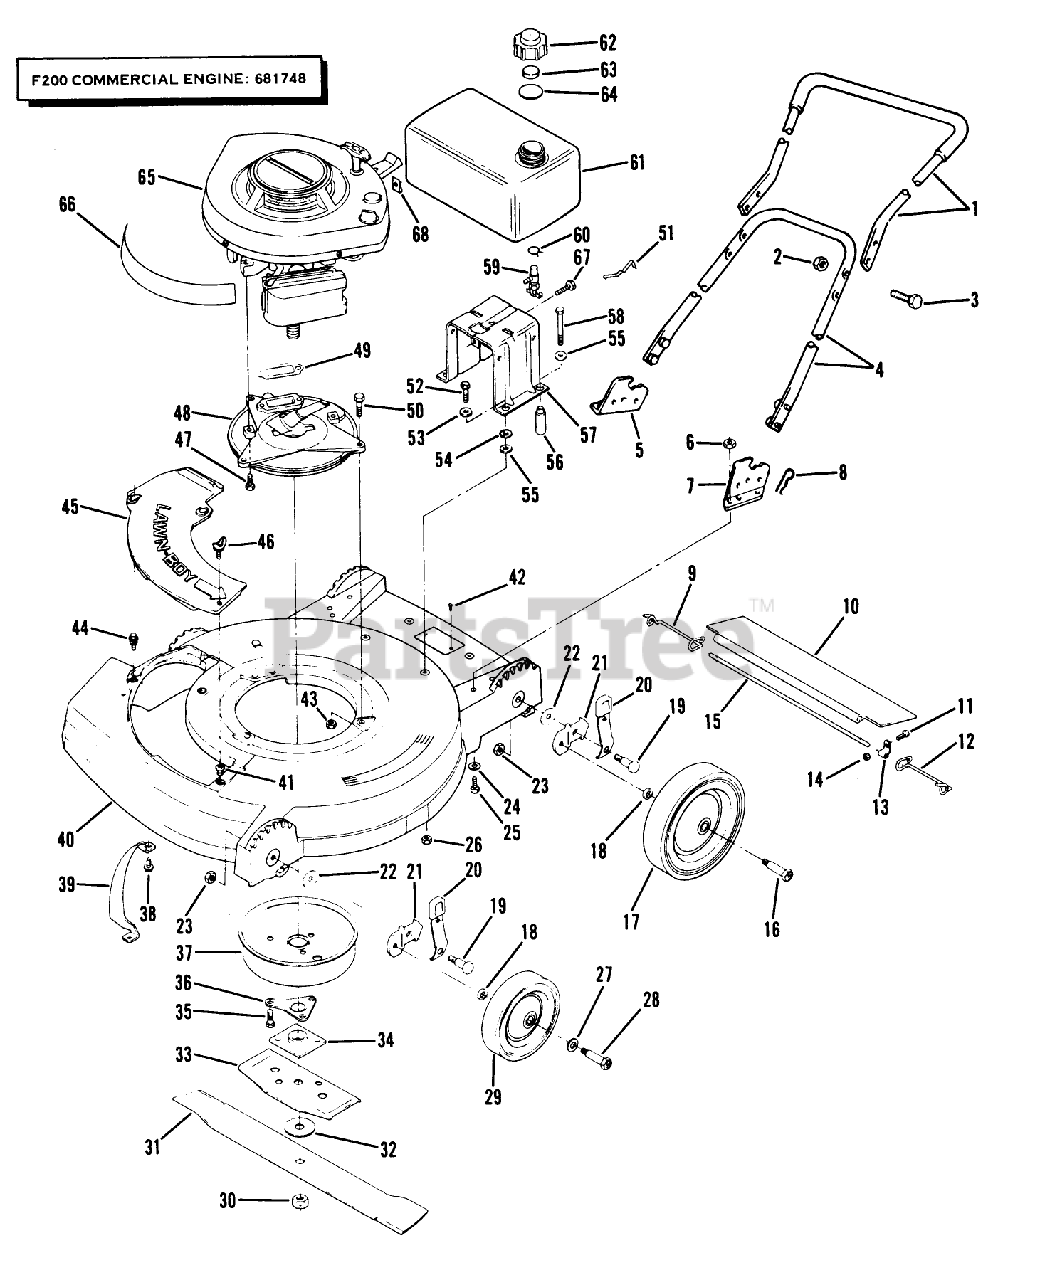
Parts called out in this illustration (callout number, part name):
2	LOCKNUT E
6	LOCKNUT E
9	SPRING;TRAILING SHIELD RH
10	SHIELD
12	SPRIG T/SHLD ASOC
13	CLAMP ROD KMC
14	LOCKNUT E
15	ROD 21" ADVANCE
16	BOLT-SHOULDER
18	WASHER WROUGHT
22	WASHER
23	LOCKNUT
24	WASHER
25	BOLT RB&W
26	LOCKNUT E
28	BOLT WHEEL
30	NUT-BLADE
32	WASHER
34	PLATE AND COLLAR ASM
35	SCREW
36	SUPPORT F
39	BAR-TOE
43	NUT-LOCK F
45	COVER PLATE
46	WING SCREW LAWRE
47	SCREW V
50	SCREW
51	SPRING
53	WASHER
55	WASHER
58	BOLT PIONEER
59	VALVE&SCREEN SM
60	CLAMP - HOSE S
63	GASKET S
64	BAFFLE - FOAM SM
67	SCREW S
68	NUT-SPEED
